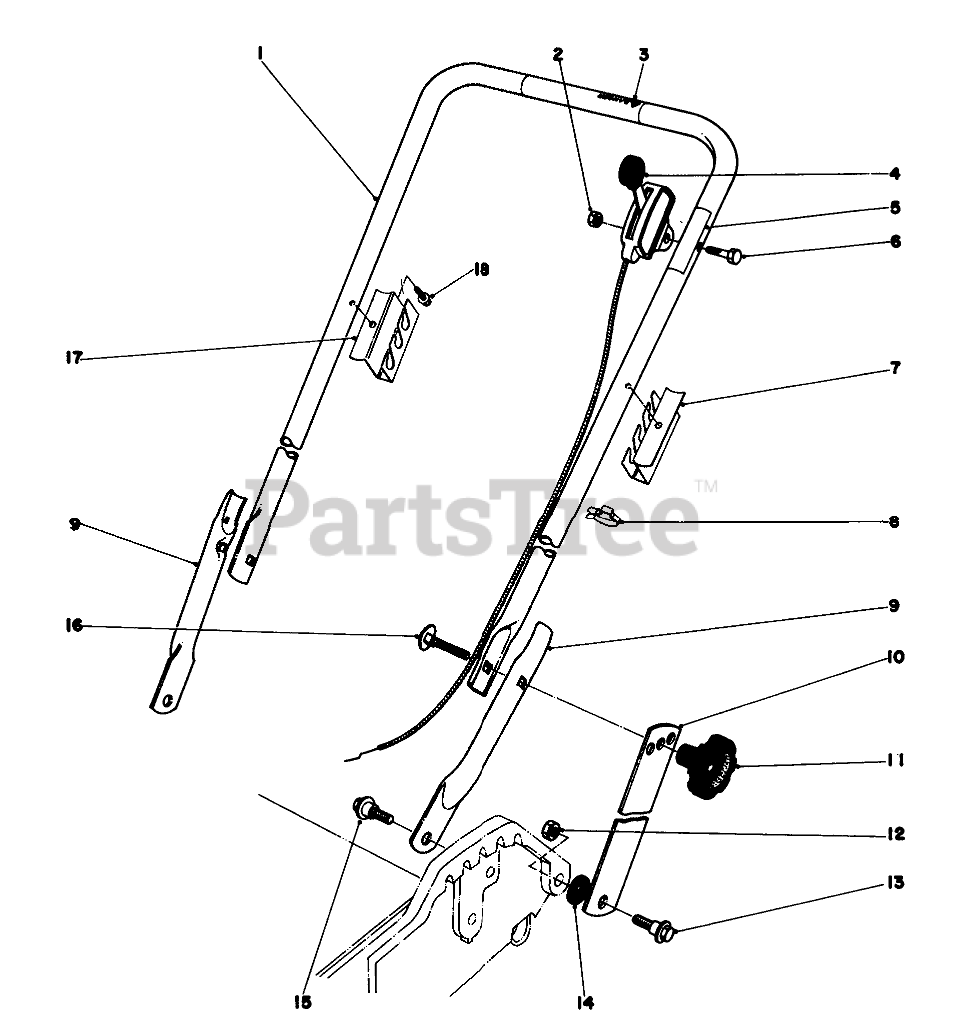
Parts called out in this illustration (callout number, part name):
1	Handle-Upper
2	NUT-LOCK
3	Decal Danger (French & Dutch)
4	Throttle Control
5	Decal Throttle Control
6	SCREW-HH
7	SUPPORT BAG LH
9	Hand-Lower
10	18" HANDLE LATCH
12	Nut
13	SCREW-SHOULDER
14	SPACER
15	SCREW-SHOULDER
16	SCREW-HANDLE
17	SUPPORT BAG RH
18	SCREW-HWHTF
